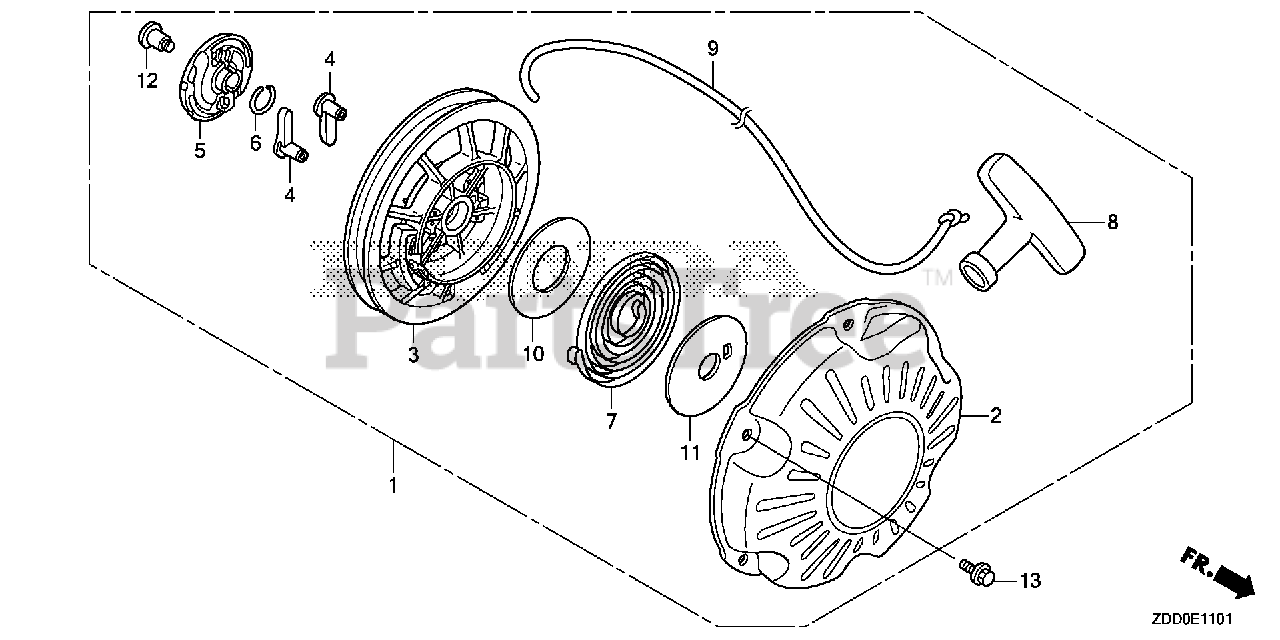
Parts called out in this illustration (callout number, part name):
1	STARTER ASSY., RECOIL *R280* (POWER RED)
2	CASE, RECOIL STARTER *R280* (POWER RED)
3	REEL, RECOIL STARTER (BLACK)
3	REEL, RECOIL STARTER
4	RATCHET, STARTER
5	GUIDE, RATCHET
6	SPRING, FRICTION
7	SPRING, RECOIL STARTER
8	KNOB, RECOIL STARTER
8	GRIP, STARTER
9	ROPE, RECOIL STARTER
10	PLATE, SIDE
11	PLATE, SLIDE
12	SCREW, SETTING (ENGINE NO.)
13	BOLT, FLANGE (6X8)
